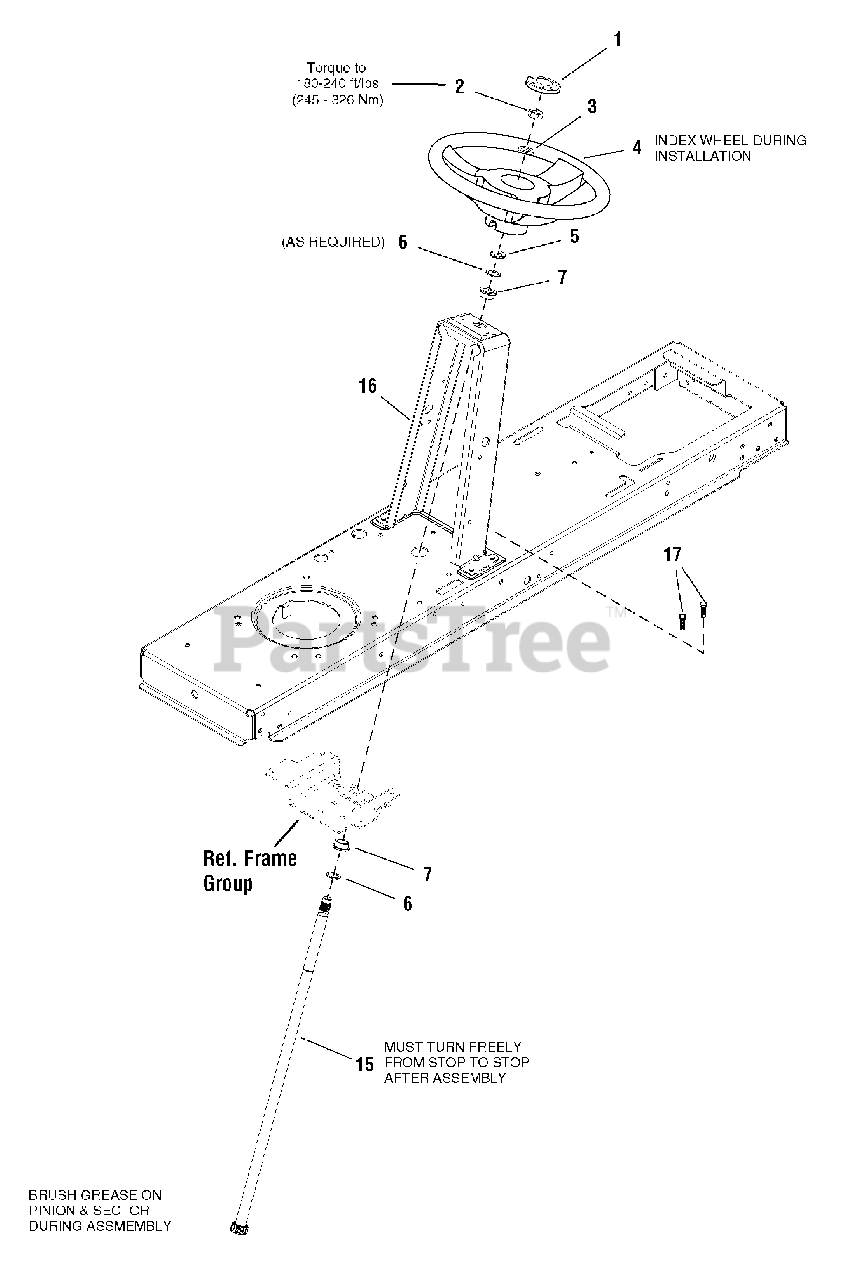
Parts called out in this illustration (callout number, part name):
1	CAP, Steering Wheel, Plain
2	NUT, Hex Lock, ESNA Light, 5/8-18, Thin
3	WASHER, 5/8
4	STEERING WHEEL, w/Aluminum Insert
5	RING, Klipring Extension
6	WASHER
7	BUSHING, Steering
15	SHAFT, Steering Gear & Spline Yellow
16	TOWER
17	CAPSCREW, Hex Washer Head, Taptite, 5/6-18 x 5/8
